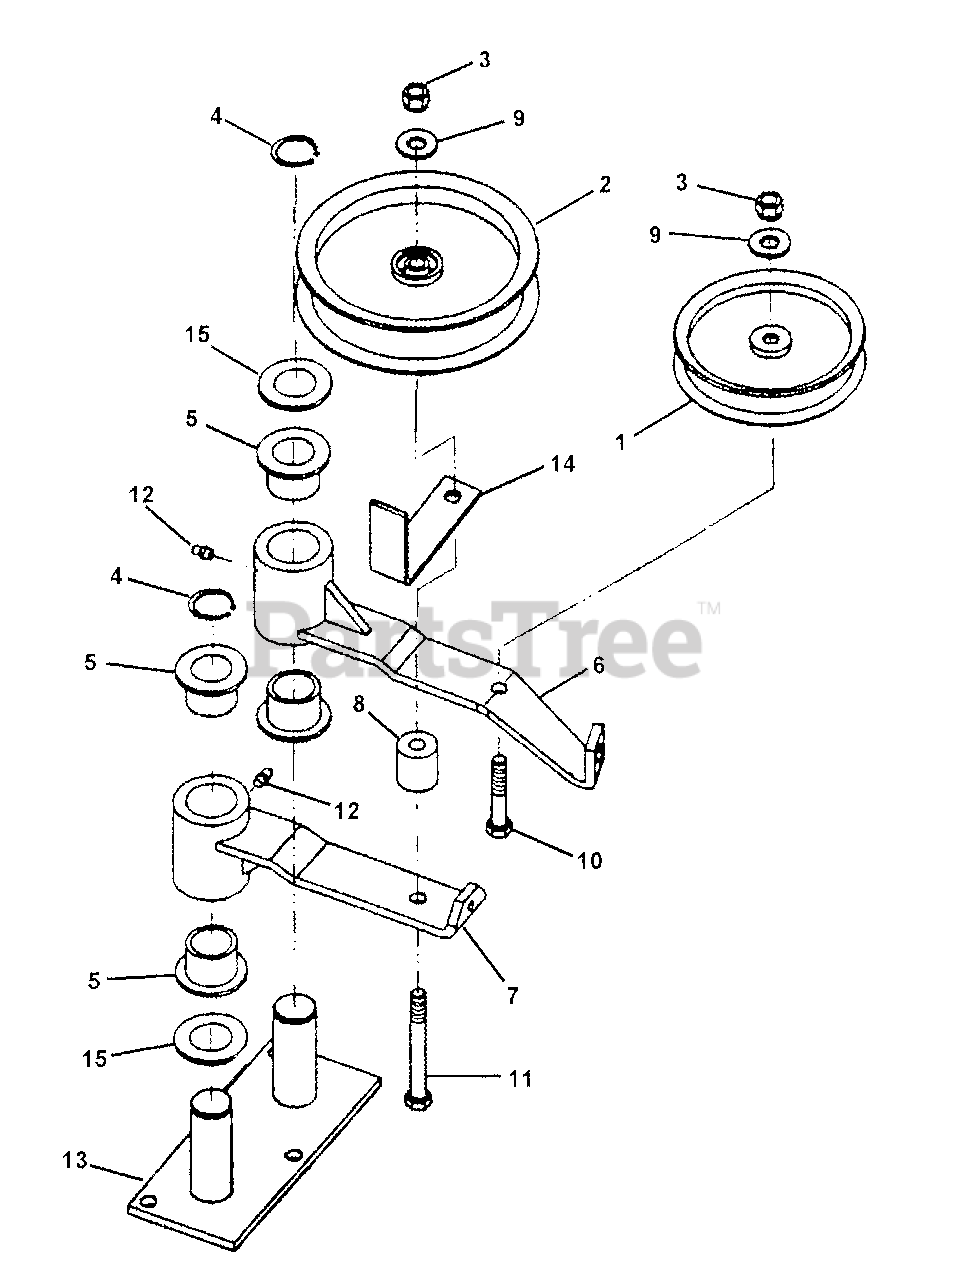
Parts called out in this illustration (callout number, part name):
1	PULLEY, Idler
2	PULLEY, Flat Idler, 5" O.D.
3	NUT, 3/8-16 Hex Center Lock, GR 5 or B
4	RING, 1" External Retaining
5	BUSHING
6	WELDMENT, Idler Arm, Secondary
7	WELDMENT, Idler Arm, Primary
8	SPACER, Idler Pulley
9	WASHER, 3/8" Flat
10	BOLT, 3/8-16 X 2, GD5, CZ
11	BOLT, 3/8-16 x 3-1/4" Hex Head Cap, GR 5
12	FITTING, 1/4-28 Straight Lube
13	WELDMENT, Idler Pivot
14	RETAINER, Belt - Idler
15	BUSHING, Machine
